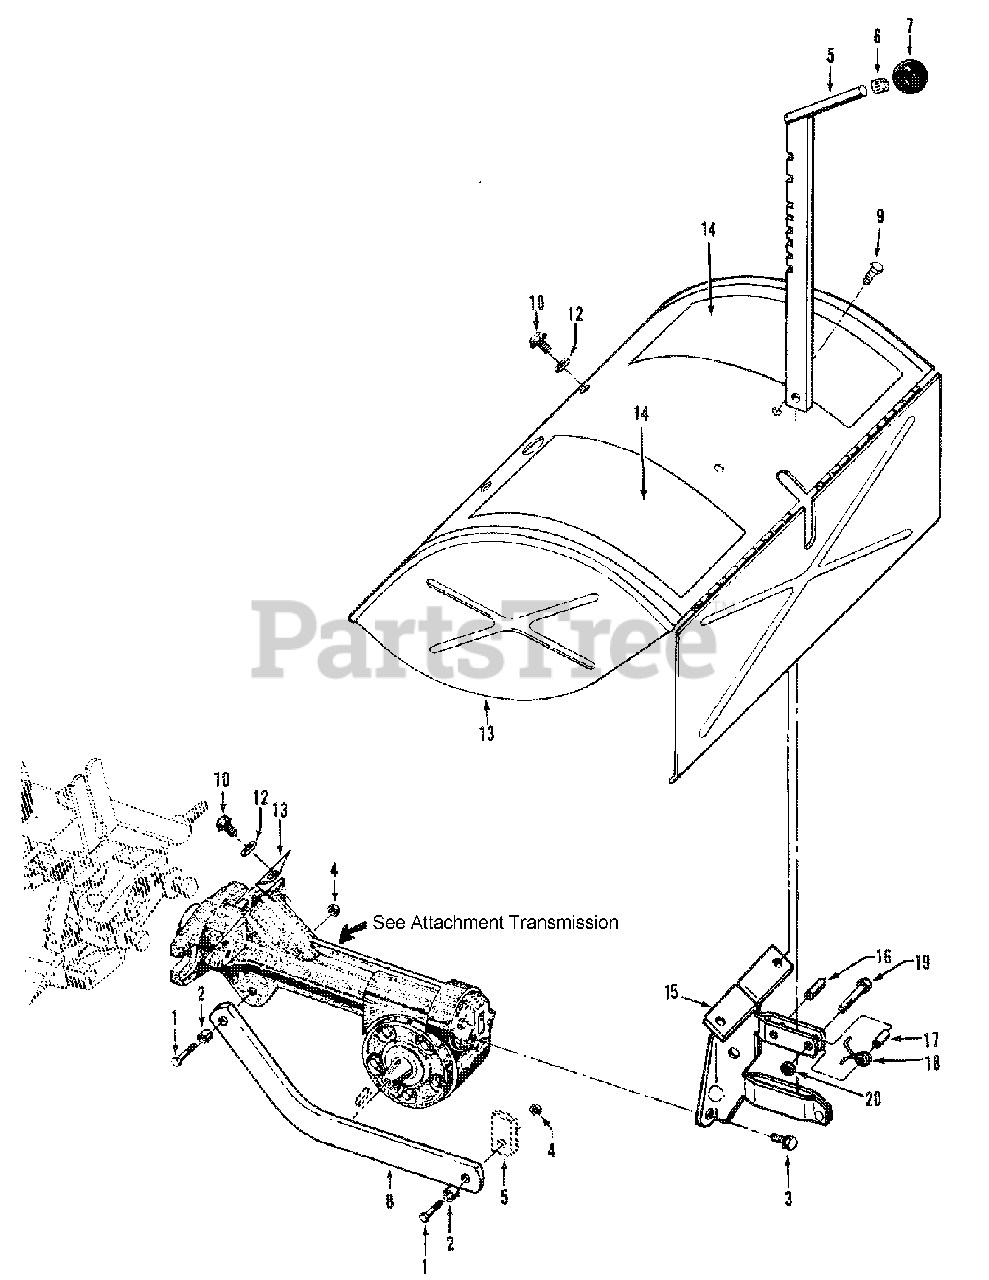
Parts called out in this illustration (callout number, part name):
1	Bolt-hex hd., 3/8-16 x 1-1/4"
2	Bushing-19/64" (.300" lg.)
3	Bolt-flanged hex, 5/16-18 x 5/8"
4	Nut-hex, 3/8"-16
5	Bar-depth regulator
6	Ring-retaining
7	Knob-depth regulator
8	Bar-drag, depth regulator
9	Screw-thread-forming,1/4-20 x 1/2"
10	Bolt-flanged hex hd.,5/16-18 x 3/4"
12	Washer-flat, 5/16"
14	Decal-hood, operating inst. (LH)
14	Decal-hood, operating inst. (RH)
16	Pin-roll (spirol) 1/4" x 1"
17	Spacer, Spilt
19	Bolt-hex hd., 1/4-20 x 1"
20	Locknut-1/4"-20
